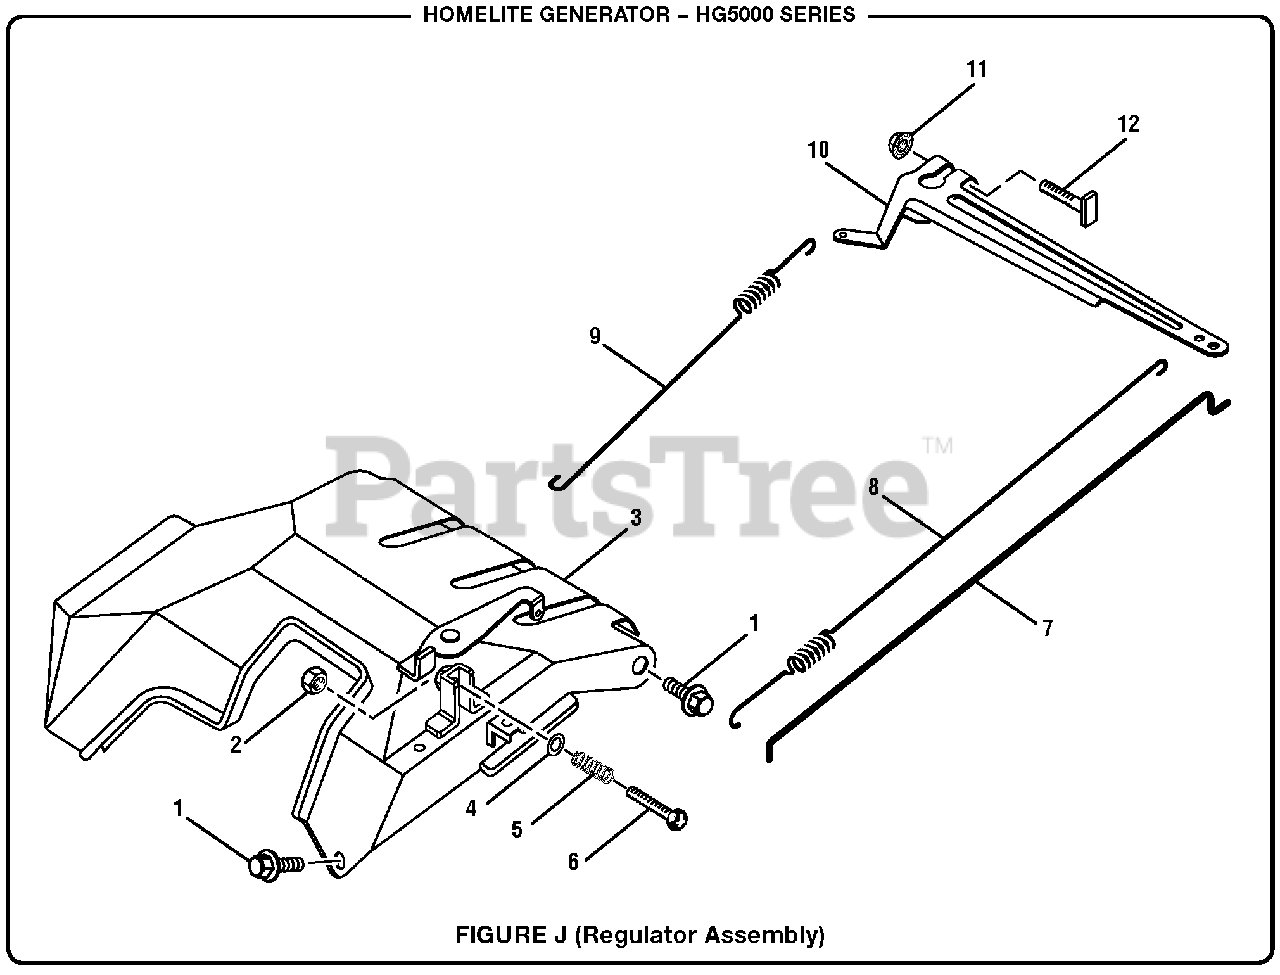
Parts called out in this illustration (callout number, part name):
1	Bolt (M6 x 12 Flange)
2	Hex Nut (M5)
3	Engine Cover
4	Washer (M5)
6	Screw (M5 x 40)
8	Regulator Spring (Fine)
9	Regulator Spring (Back)
10	Regulating Arm
11	Flange Nut (M6)
12	Lock Bolt
